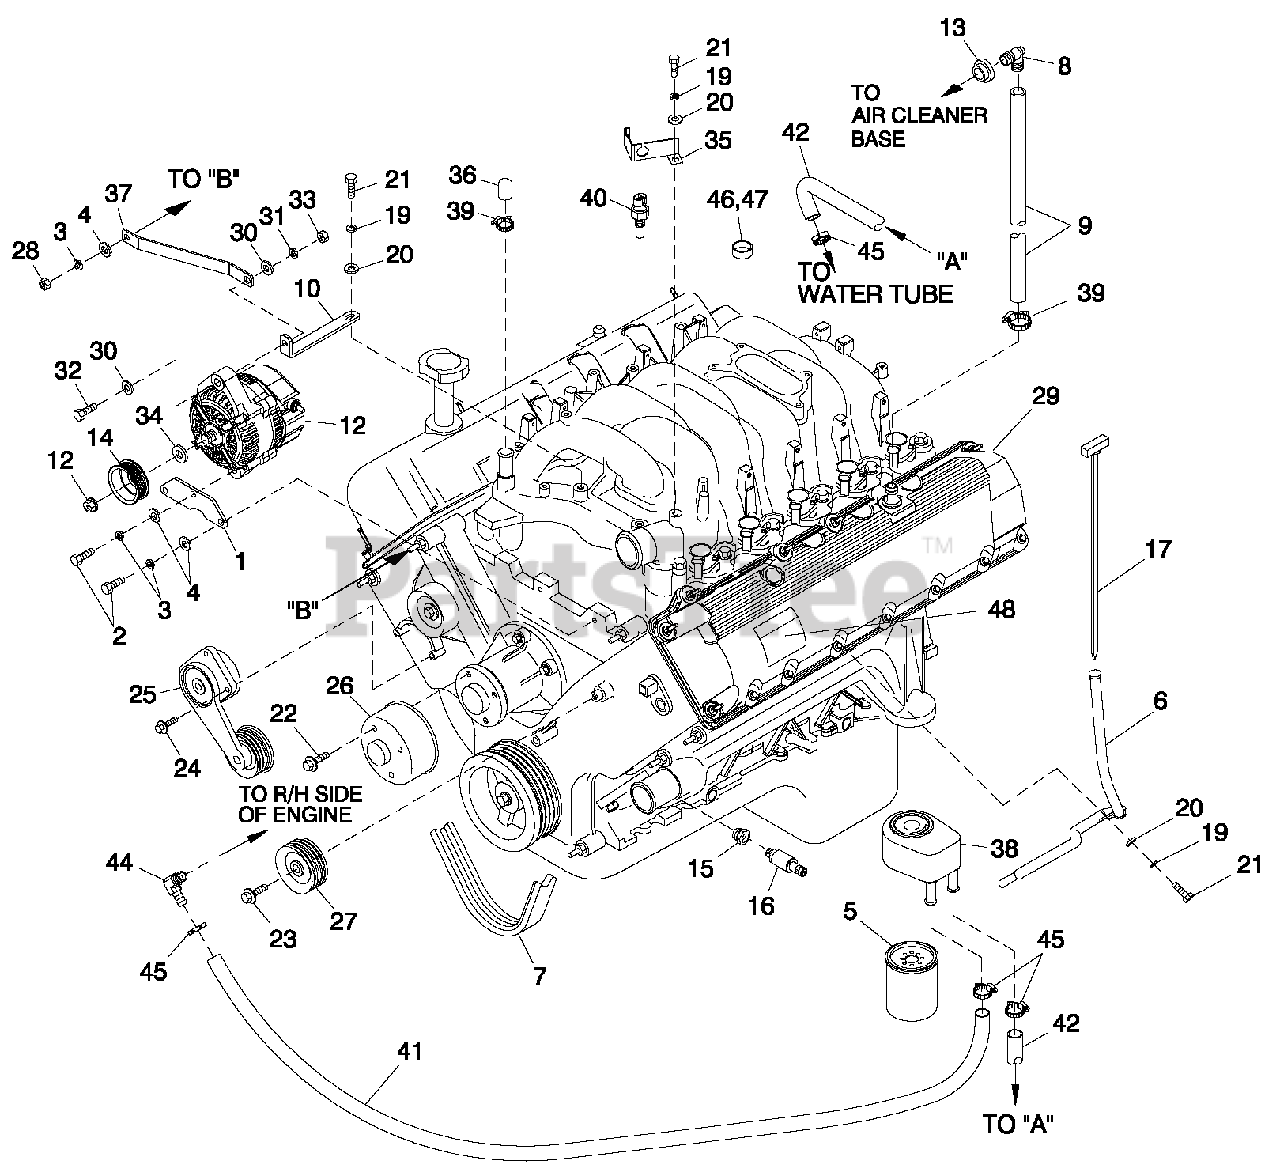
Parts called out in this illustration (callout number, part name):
1	BRACKET,D.C. ALTERNATOR LOWER
2	SCREW HHC M8-1.25X 20 G8.8
3	WASHER LOCK M8-5/16
4	WASHER FLAT 5/16-M8 ZINC
5	OIL FILTER, FORD V-10 ENGINE
6	DIPSTICK TUBE, FORD 6.8L
7	BELT SERPENTINE (65.0" LG) (1800 RPM)
8	BARBED EL 90 3/4 PLASTIC
9	HOSE 3/4 ID SAE-30R2 (16.75+LG)
10	BRACKET DC ALTERNATOR UPPER
12	ALTERNATOR DC W/OUT PULLEY
13	GROMMET
14	PULLEY 80 OD DC ALTERNATOR (1800 RPM)
15	BUSHING REDUCER 3/8 TO 1/8 GAL
16	SENDER OIL PRESSURE 1/8" NPT
17	DIPSTICK 6.8L FORD
19	WASHER LOCK M6-1/4
20	WASHER FLAT 1/4 ZINC
21	SCREW HHC M6-1.0X 20 G8.8
22	BOLT WATER PUMP PULLEY
23	BOLT GROOVED IDLER PULLEY
24	BOLT BELT TENSIONER
25	TENSIONER ENG. AUTOMATIC BELT
26	PULLEY WATER PUMP FORD (1800RPM UNITS)
27	PULLEY GROOVED ENGINE IDLER
28	NUTHEXM8-1.25 G8 YEL CHR
29	ENGINE G6.8L G3V-10
30	WASHER FLAT 3/8-M10 ZINC
31	WASHER LOCK M10
32	SCREW HHC M10-1.5 X 45 G8.8 FT
33	NUTHEXM10-1.5 G8 YEL CHR
34	SPACER DC ALTERNATOR PULLEY
35	BRACKET SIGNAL CONDITIONER
36	CAP RUBBER
37	BRACKET DC ALT STABILIZER
38	OIL COOLER FORD (150KW 3600RPM)
39	CLAMP HOSE #10 .56-1.06
40	TEMPERATURE SENDER DELPHI
41	HOSE OIL COOLER PREFORMED 3/4 (150KW 3600RPM)
42	HOSE OIL COOLER (150KW 3600RPM)
44	BARBED EL 45 3/8NPT X 5/8OD
45	CLAMP HOSE #10 .56-1.06 (150KW 3600RPM)
46	PLUG EXPANSION 14 OD
47	ADHESIVE LOCTITE 620
48	DECAL EMISSION CTRL INFO 6.8L
